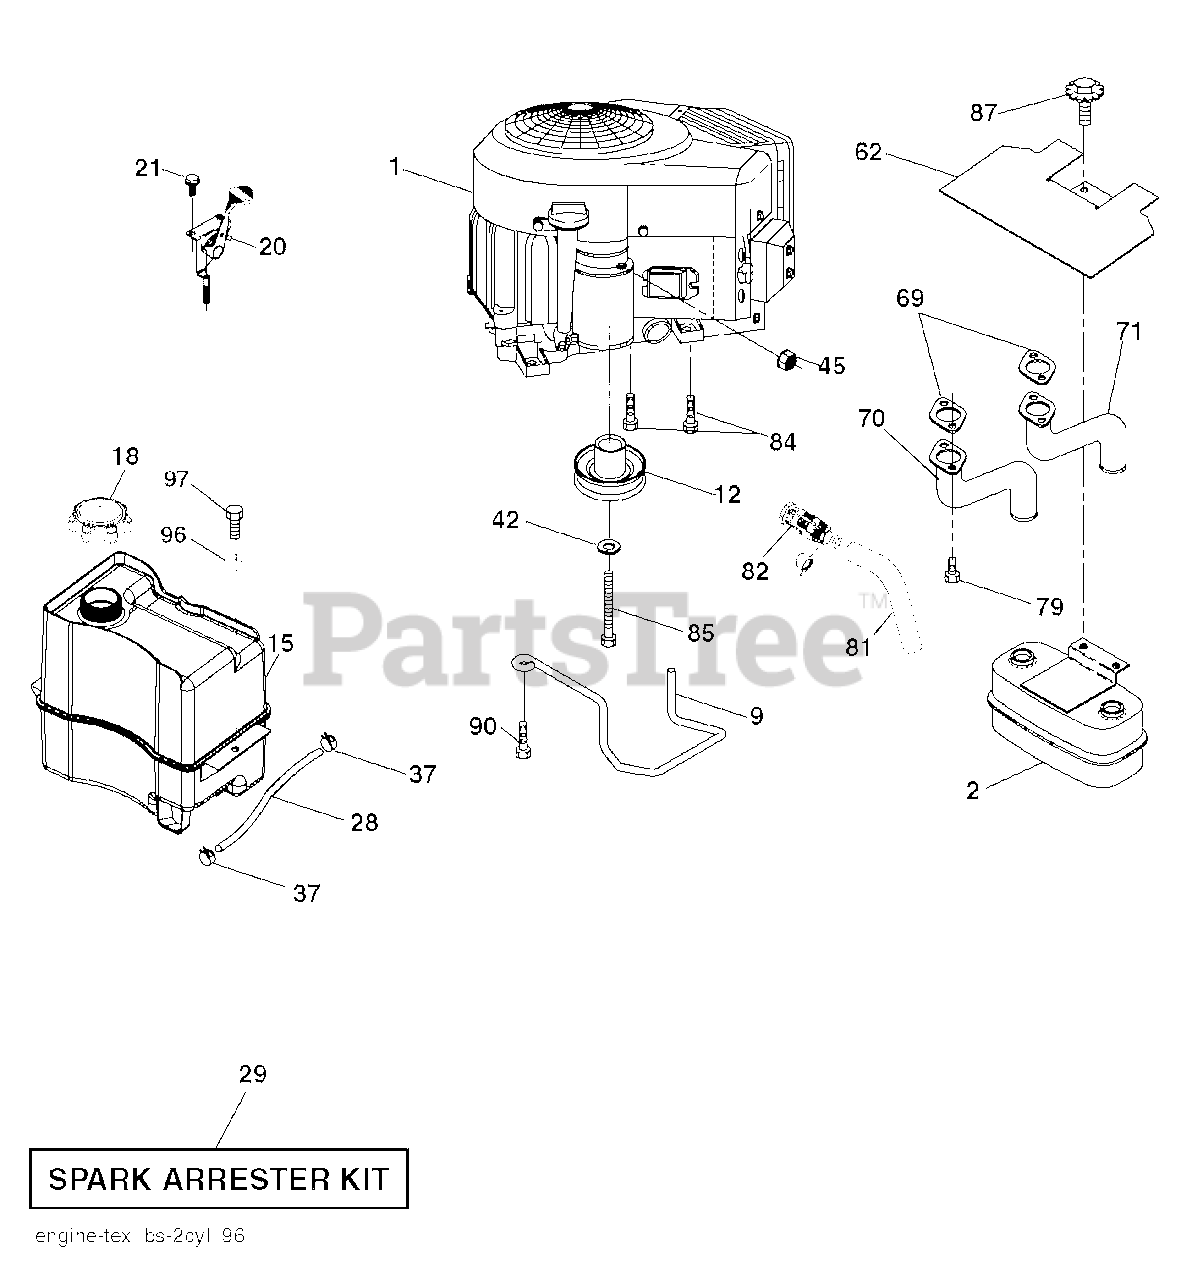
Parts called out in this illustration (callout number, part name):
2	MUFFLER.TWIN.CYL.LOW.TONE
9	KEEPER.BELT.ENGINE.4.2
12	PULLEY ENGINE
15	TANK.ASSEMBL.2.5GAL.NON-EPA
18	CAP ASM.FUEL.2.25"FR.
20	CONTROL.TH/CK.COBRA.B&S.TWN.
21	SCREW.#10 X 0.750.BOS (2 2)
28	LINE.FUEL.20
29	KIT.SPARK ARRESTOR(392390 B&S)
37	HOSE CLAMP
42	LOCKWASHER
45	NUT
62	SHIELD.HEAT.MUFFLER
69	GASKET.MUFFLER
70	RP.EXHAUST.TUBE.LH.BS/TWIN
71	RP.EXHAUST.TUBE.RH.BS/TWIN
79	SCREW.SOCKET.HEAD.5/16-18
81	TUBE, DRAIN OIL ASM.
82	VALUE.OIL.DRAIN
84	SCREW.3/8-16
85	BOLT HEX 7/16-20X4-1/4"
87	BOLT, 5/16-18 X 1 3/4
90	SCREW 3/8-16X1
97	SCREW HEXWSHR 1/4-20X3/4
